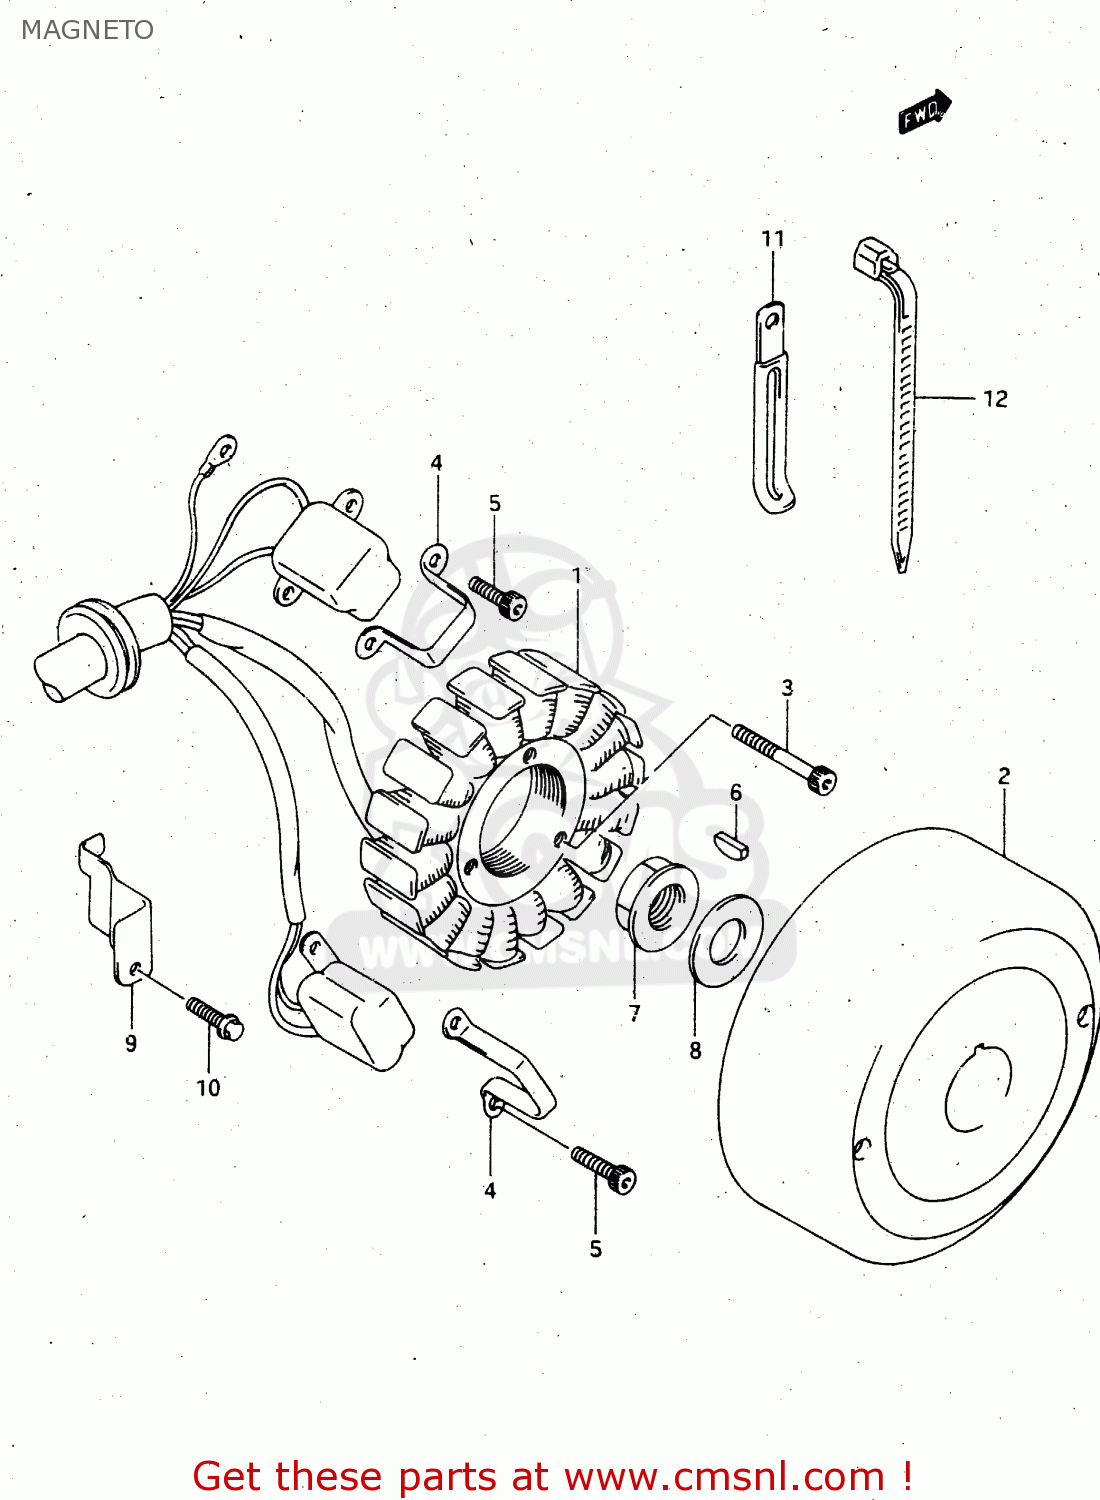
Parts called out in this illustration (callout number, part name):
1	STARTER ASSY
2	ROTOR ASSY
3	BOLT
4	CLAMP,PLSR COI
5	BOLT
6	KEY
7	NUT
8	WASHER(12X27X2)
9	CLAMP,MAGNETO LEAD WIRE
10	BOLT
11	CLAMP
12	CLAMP(L:165)
